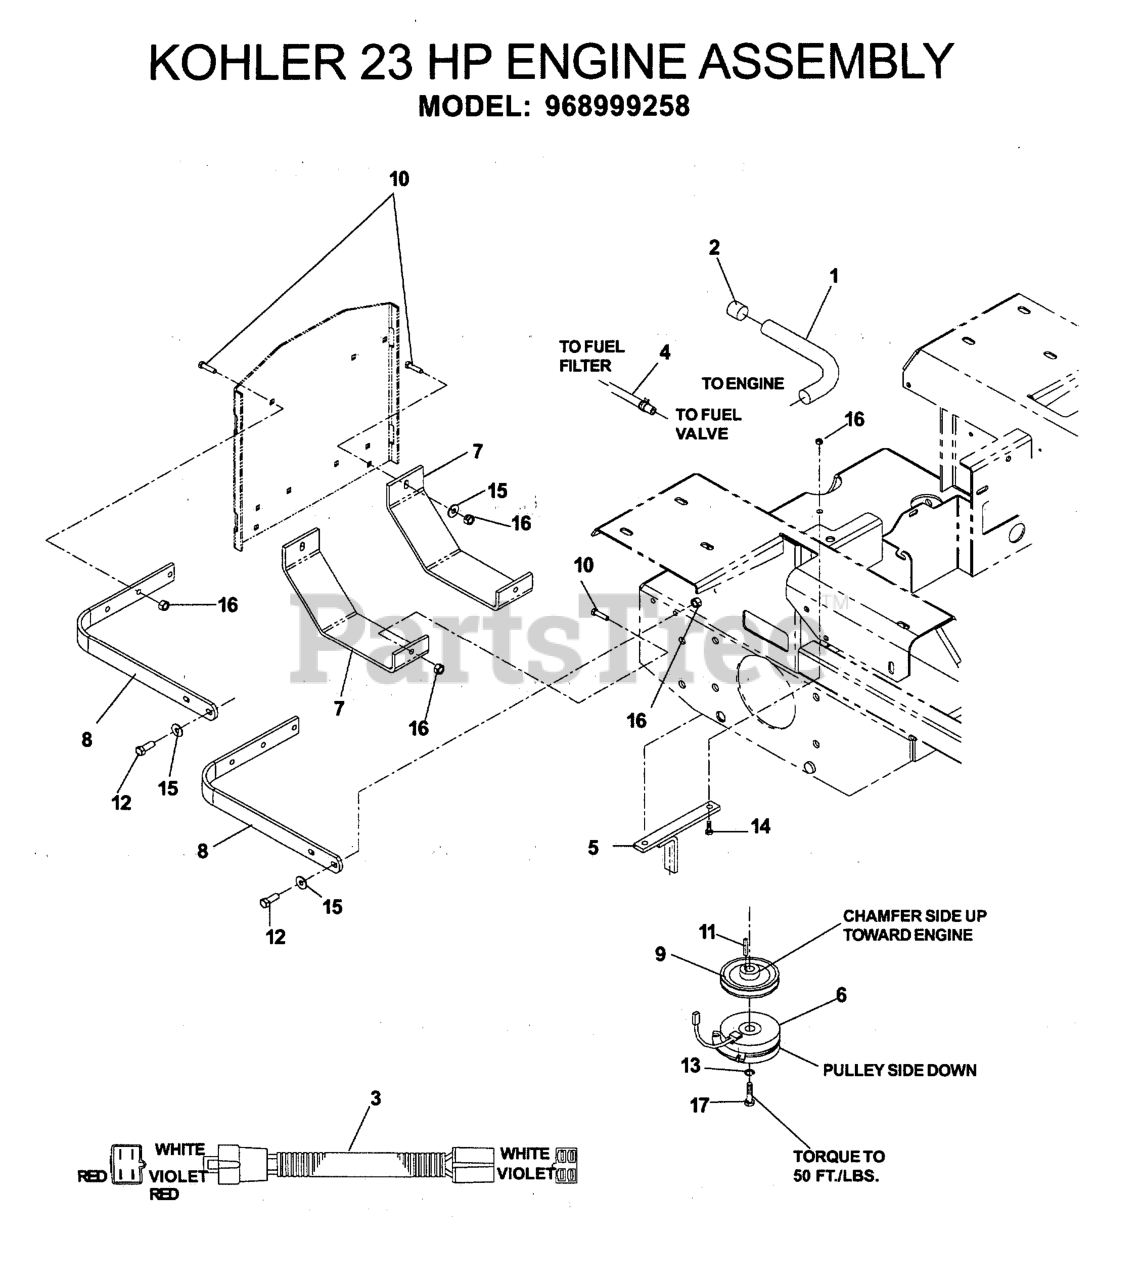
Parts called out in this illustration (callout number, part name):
1	OIL DRAIN HOSE
3	KOH PIGTAIL
4	FUEL LINE 13"
5	CLUTCH TIE DOWN
6	CLUTCH-200 FT LB(RPLS 5218-102
7	SKID PLATE
8	ENGINE SHROUD BRKT
10	RHSSNB 5/16C X 1.0
11	KEY, 1/4 SQ X 1 1/4
12	HCS 5/16C X 1
13	WASHER 7/16 LOCK
14	HCS 5/16C X 1 3/4
15	WASHER 5/16 FLAT
16	NUT 5/16 NYLOC
17	BOLT 7/16F X 2 1/2
